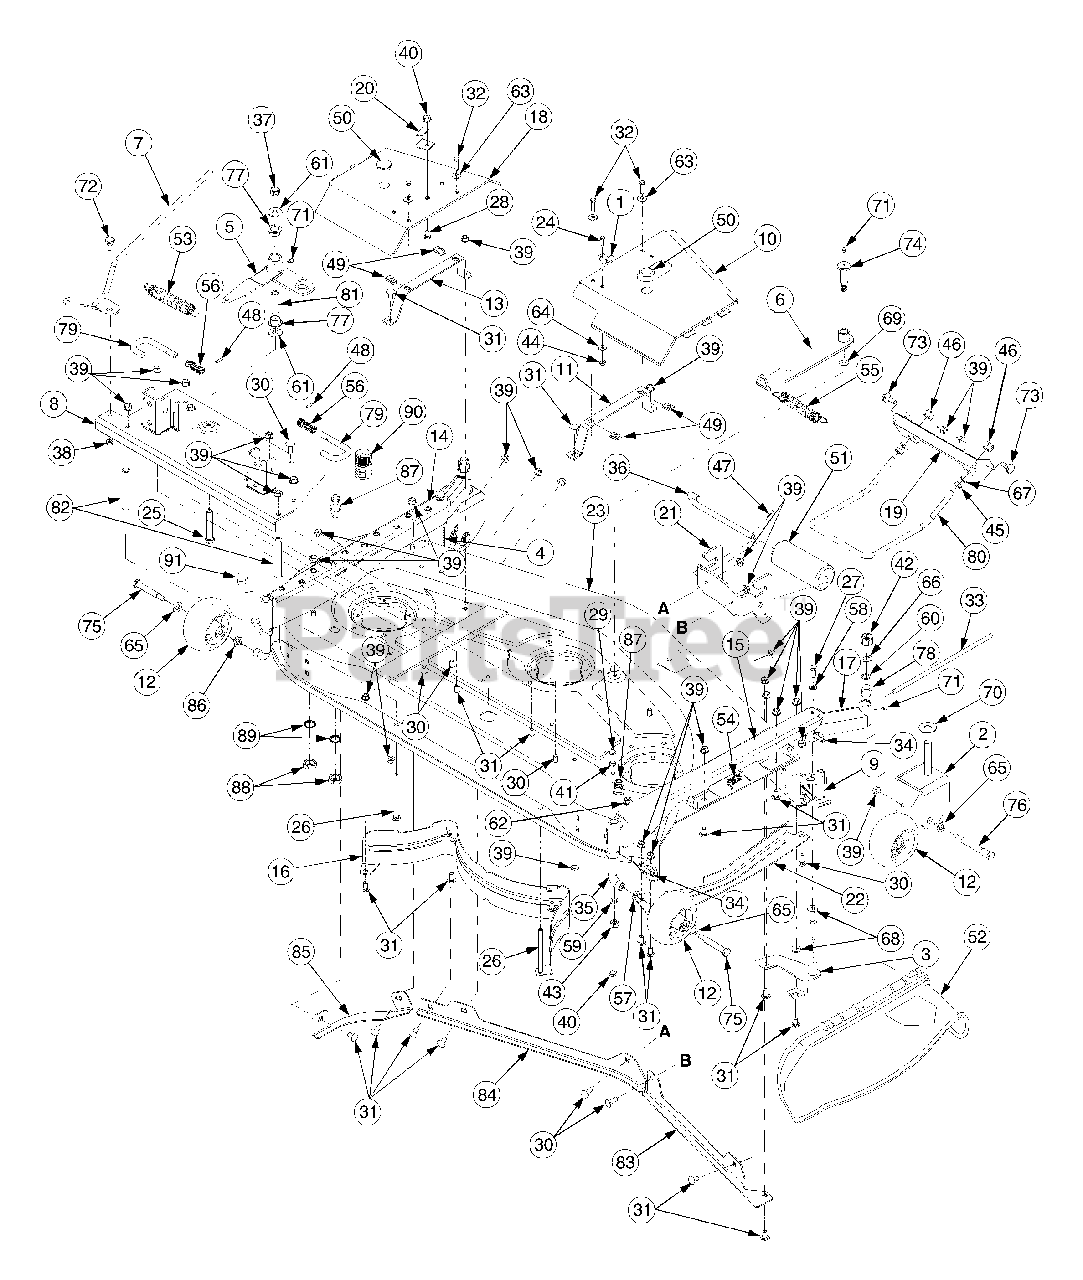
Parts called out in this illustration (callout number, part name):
1	Bracket, Hook Retainer
3	Spindle, Adjustment RH
4	Spindle, Adjustment LH
5	Bracket, Idler
24	Screw, Hex Cap 1/4-20 x .62 GR5
25	Screw, Hex Cap, 1/2-20 x 3.0 GR8
26	Carriage, Bolt 3/8-16 x 5.0 GR5
27	Screw, Hex Cap, 3/8-16 x .88 GR5
28	Screw, Hex Cap, 5/16-18 x .5 GR5
29	Screw, Hex Cap, 5/16-18 x 2.25 GR5
30	Carriage, Bolt 3/8-16 x 1.0
31	Carriage, Bolt 3/8-16 x .75
32	Screw, Hex Cap, 5/16-18 x 1 GR5
33	Pin, Hinged .375 x 14.06
34	Pin, Clevis w/Ball Detent
35	Axle, Castor
36	Pin, Roller 1/2 x 7.31
37	Nut, Hex Lock, 1/2-20 GRA
38	Nut, Hex Lock, 3/8-16 GRA
39	Nut, Flange Lock 3/8-16
40	Nut, Flange Lock, 5/16-18 GR5
41	Nut, Hex , 5/16-18 GR5
42	Nut, Hex Lock 5/8-11
43	Nut, Hex, 7/16-14 GR2
44	Nut, Hex Flange Lock 1/4-20
45	Nut, Hex Jam, 1/2-13 GR5
46	Nut, Hex Insert Lock, 1/2-13 GR8
47	Pin, Cotter 3/32 x 1.25
48	Pin, Spirol
49	Nut, "U" 5/16-18
50	Plug, Button
51	Roller, Front
52	Deflector, Chute
53	Spring, Extension
54	Spring, Torsion
55	Spring, Extension
56	Spring, Compression
57	Washer, Bell, .375 x .87 x .063
58	Washer, Lock 3/8" I.D.
59	Washer, Lock 7/16" I.D.
60	Washer, Wave, .625 x .885 x .015
61	Washer, Flat, .5 x 1.25 x .10
62	Washer, Flat, .535 x .93 x .09
63	Washer, Bell .34" I.D.
64	Washer, Bell .265 x .75 x .062
65	Washer, Flat, .51 x 1.0 x .06
66	Washer, Flat, .625 x 1.0 x .067
67	Washer, Lock, 1/2
68	Washer, Flat, .406 x .875 x .105
69	Washer, Flat, .469 x .875 x .105
70	Washer, Flat, 1.595 x .635 x .062 HT
71	Fitting, Lube, 3/16 Drive
72	Screw, Shoulder, .498 x .34: 3/8-16
73	Screw, Shoulder, .5 x .434: 3/8-16
74	Screw, Shoulder, .68 x 1.59
75	Screw, Shoulder, .5 x 2.5
76	Screw, Step Shoulder, 5/8-1/2 x 3.41
77	Bearing, Flange, 3/4 x .52
78	Bearing, Flange, .63 ID
79	Pin, Mower Support
80	Rod, Deck Hanger
81	Spacer, .5 x .75 x 2.07" Lg.
82	Spacer, .405" x .75 x 3.875" Lg.
86	Spacer, Shoulder
87	Nozzle, Deck Wash
88	Nut, Hex, M16-1.5
89	Washer, Lock
90	Adapter, Water Nozzle
91	Plug, Screw, M16-1.5
